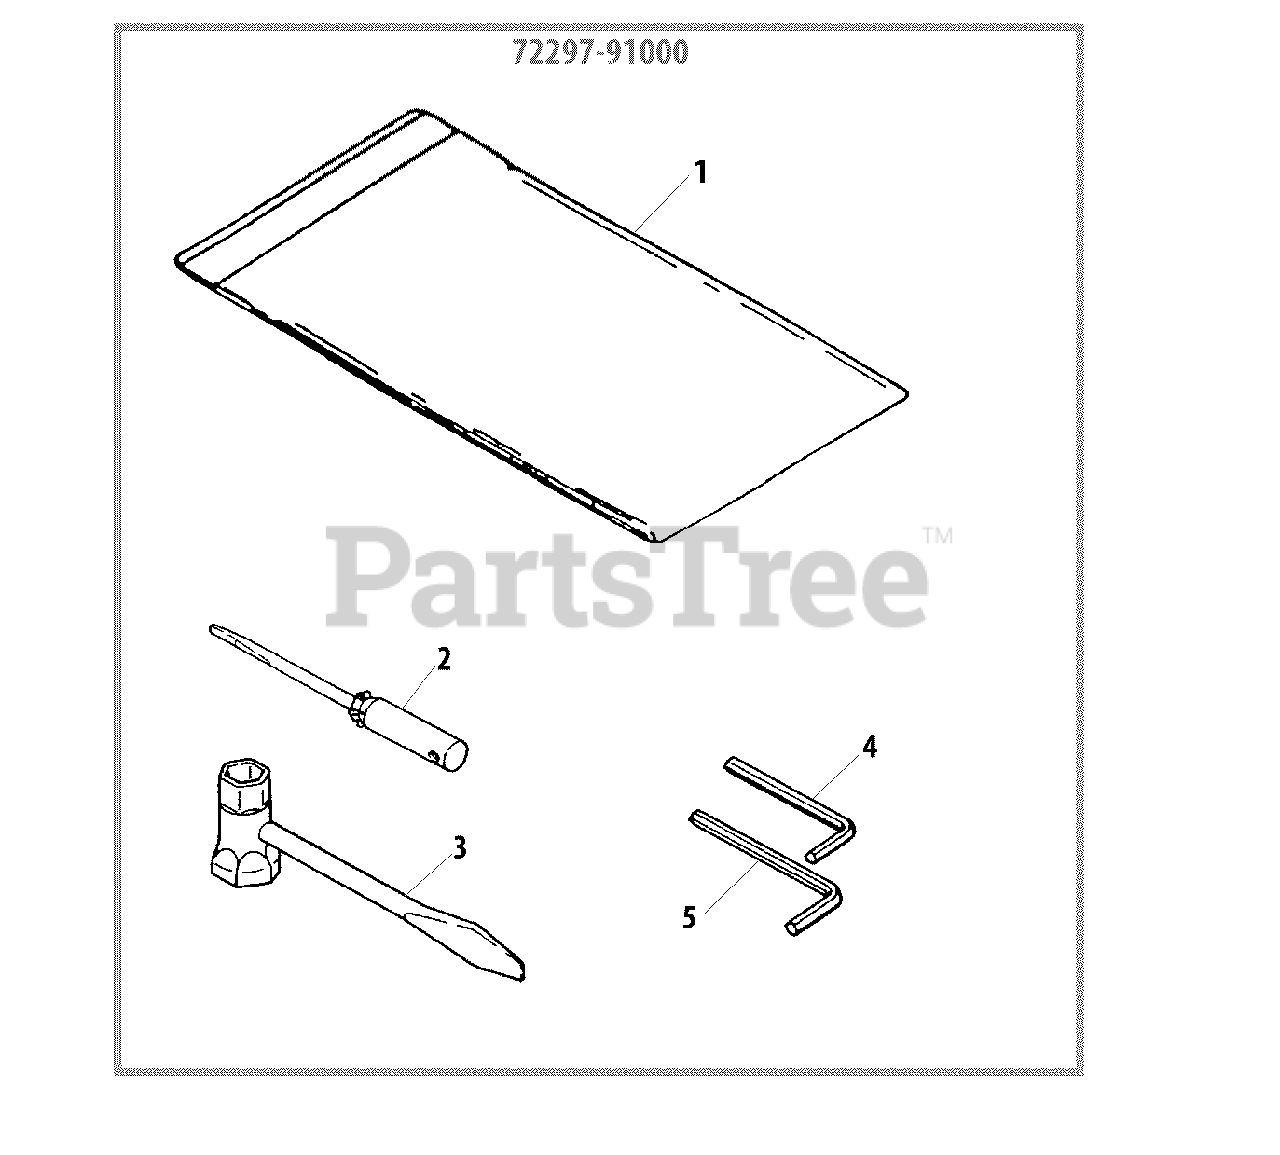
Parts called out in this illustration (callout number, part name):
1	BAG, TOOL
2	SCREWDRIVER
3	T-WRENCH - 13X19mm
4	SPANNER - 8X10mm
5	HEX KEY - 4mm
72297-91000	TOOL KIT
